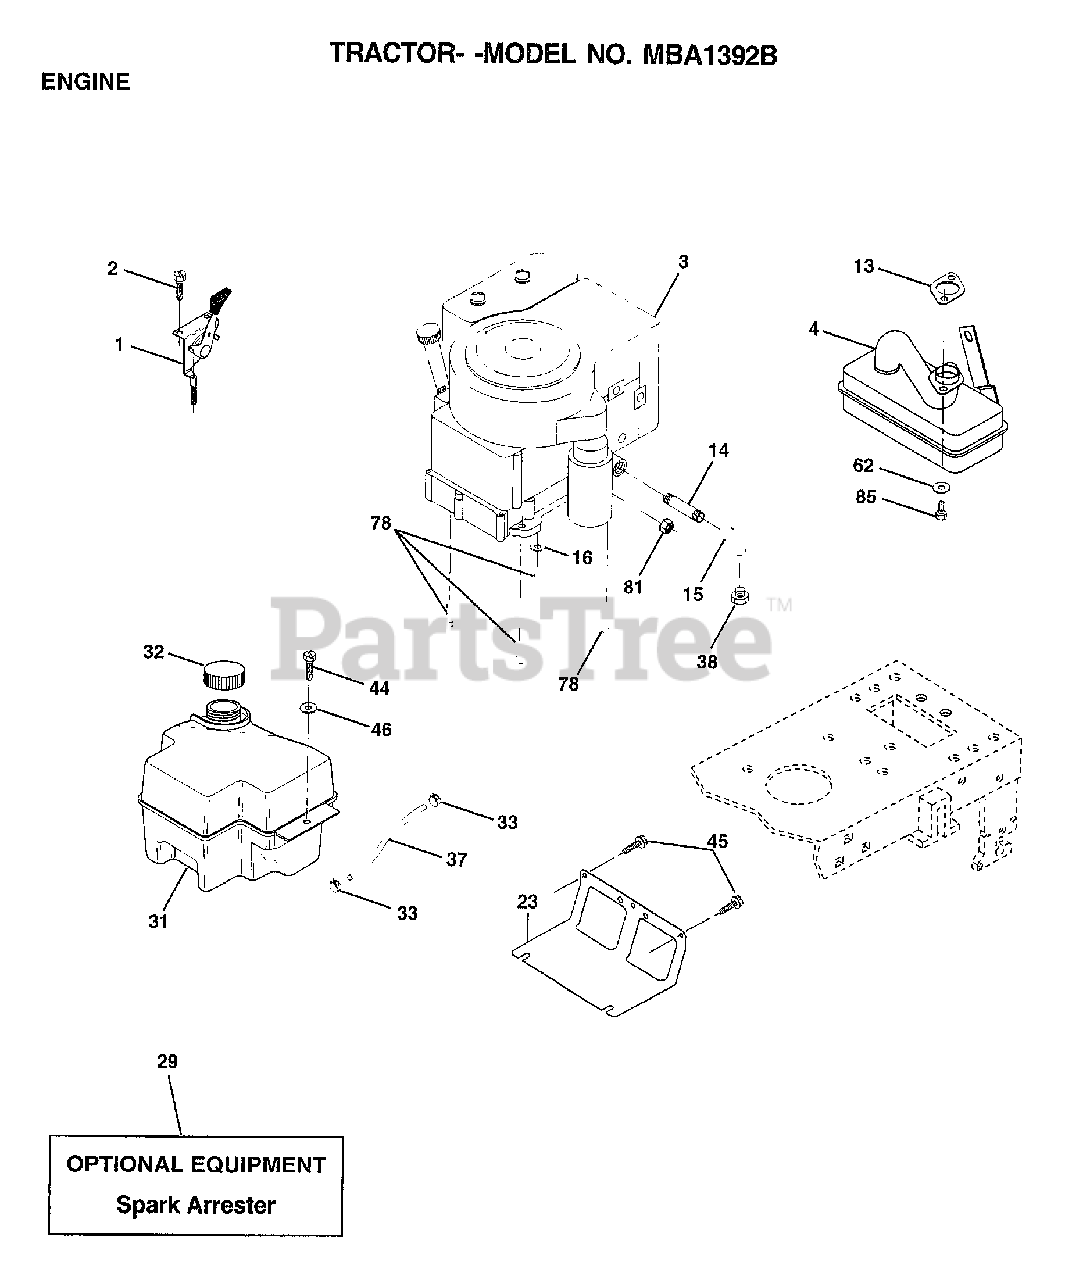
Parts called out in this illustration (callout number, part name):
1	CONTROL-THROT/CHO
2	SCREW LT
4	MUFFLER TEC. 13HP
14	PIPE NIPPLE LT
15	ELBOW
16	LOCKWASHER
23	SHIELD BROWNING
31	TANK.FUEL.FRONT.
32	CAP ASM FUEL
33	HOSE CLAMP
37	LINE FUEL
44	SCREW HEX CRT
45	SCREW
46	WASHER
62	LOCKWASHER
78	SCREW
81	NUT
85	SCREW HEX HD CAP
